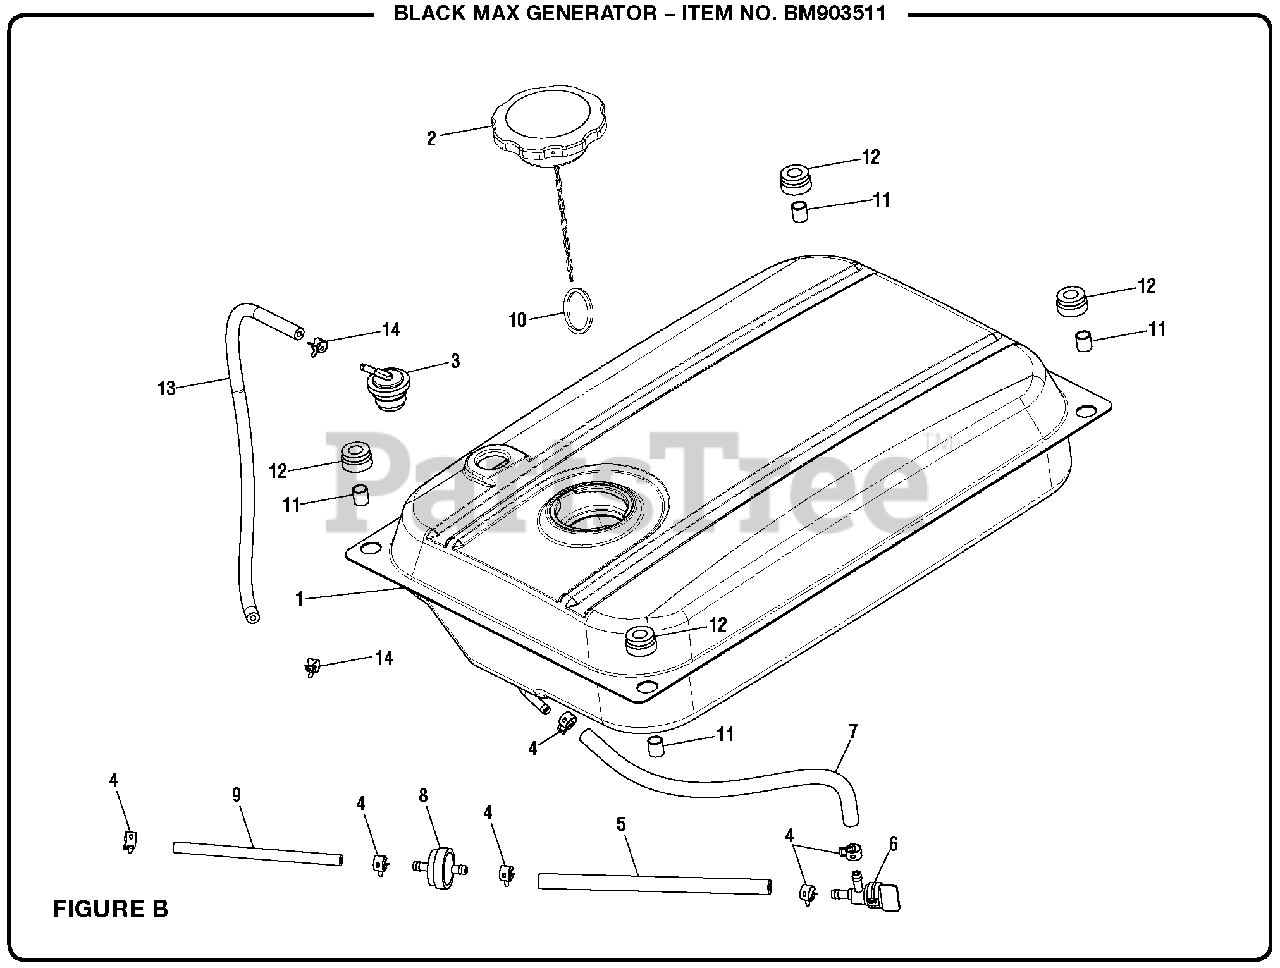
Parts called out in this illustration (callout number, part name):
1	Fuel Tank
3	Fuel Tank Vapor Vent
4	Clamp (1/2 in.)
5	Fuel Hose (45 mm)
6	Fuel Shut Off Valve
7	Fuel Hose (35 mm)
8	Fuel Filter
9	Fuel Line (144 mm)
10	Ring Clip
13	Vent Hose
14	Fuel Line Clamp (7/16 in.)
